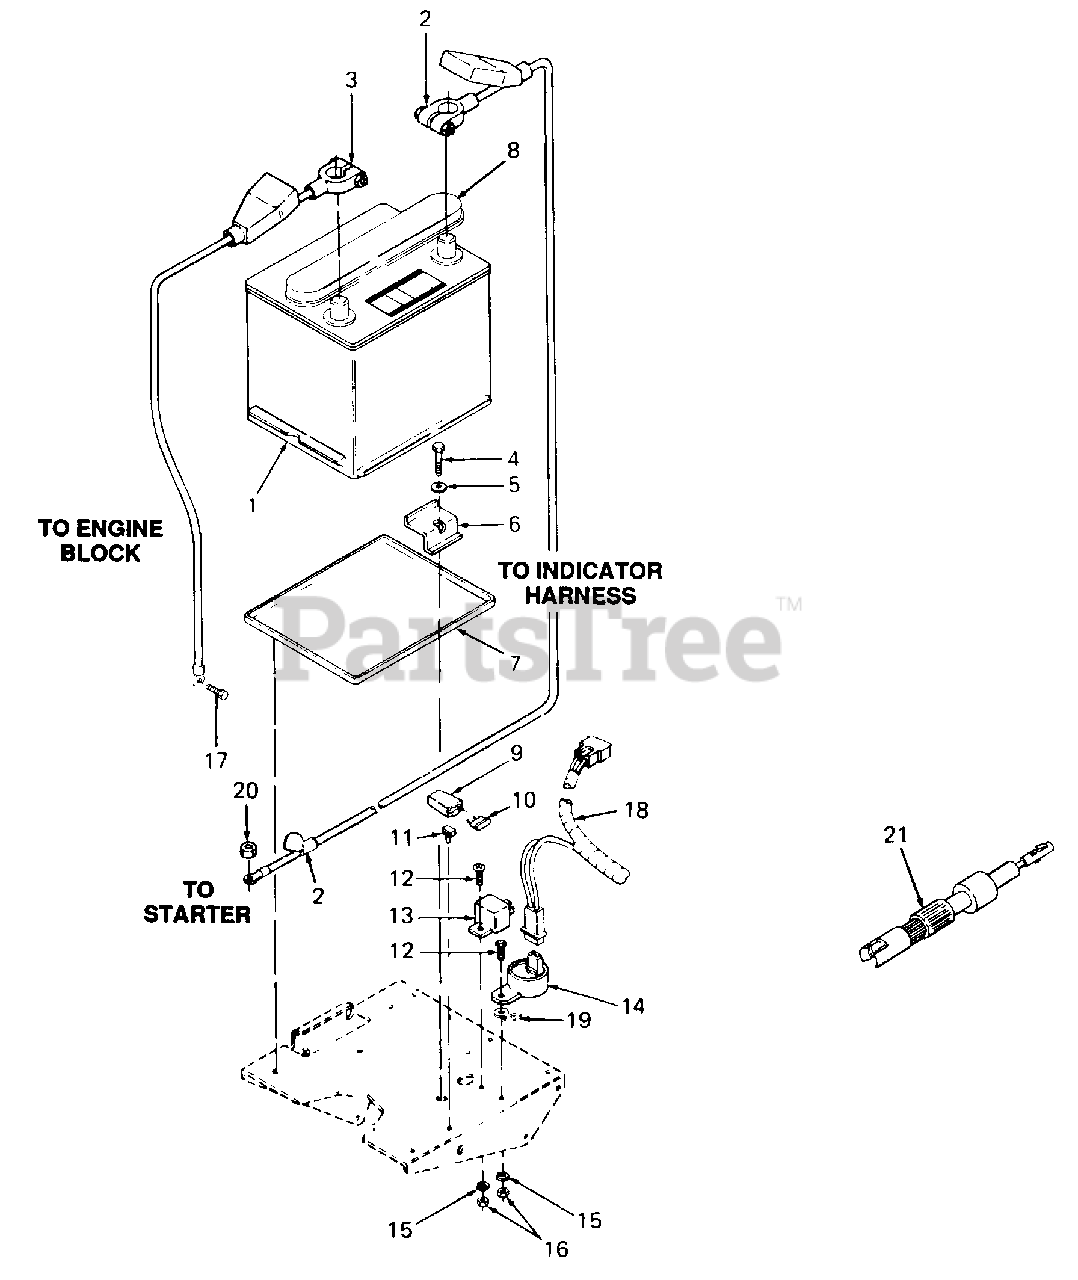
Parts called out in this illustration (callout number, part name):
1	Battery
2	Cable, Positive Battery
3	Cable, Negative Battery
4	Screw, Hex Cap, 5/16-18 X 1.38 Lg
5	Washer, Flat, .34 X .68 X .062 Thk
8	Cap, Battery Vent
9	Holder, Fuse
10	Fuse, 20 Amp
11	Clip, Fuse Holder Mtg
12	Screw, Truss Mach, #10-24 X .50 Lg
13	Relay
14	Indicator, Voltage
15	Washer, Lock, #10
16	Nut, Hex, #10-24
17	Screw, Hex Cap, M8-1.25 X 14 MM Lg
18	Main Harness
19	Lug, Quick Connect
20	Nut, Hex, M8-1.25 GR8.8
21	Diode Assy
